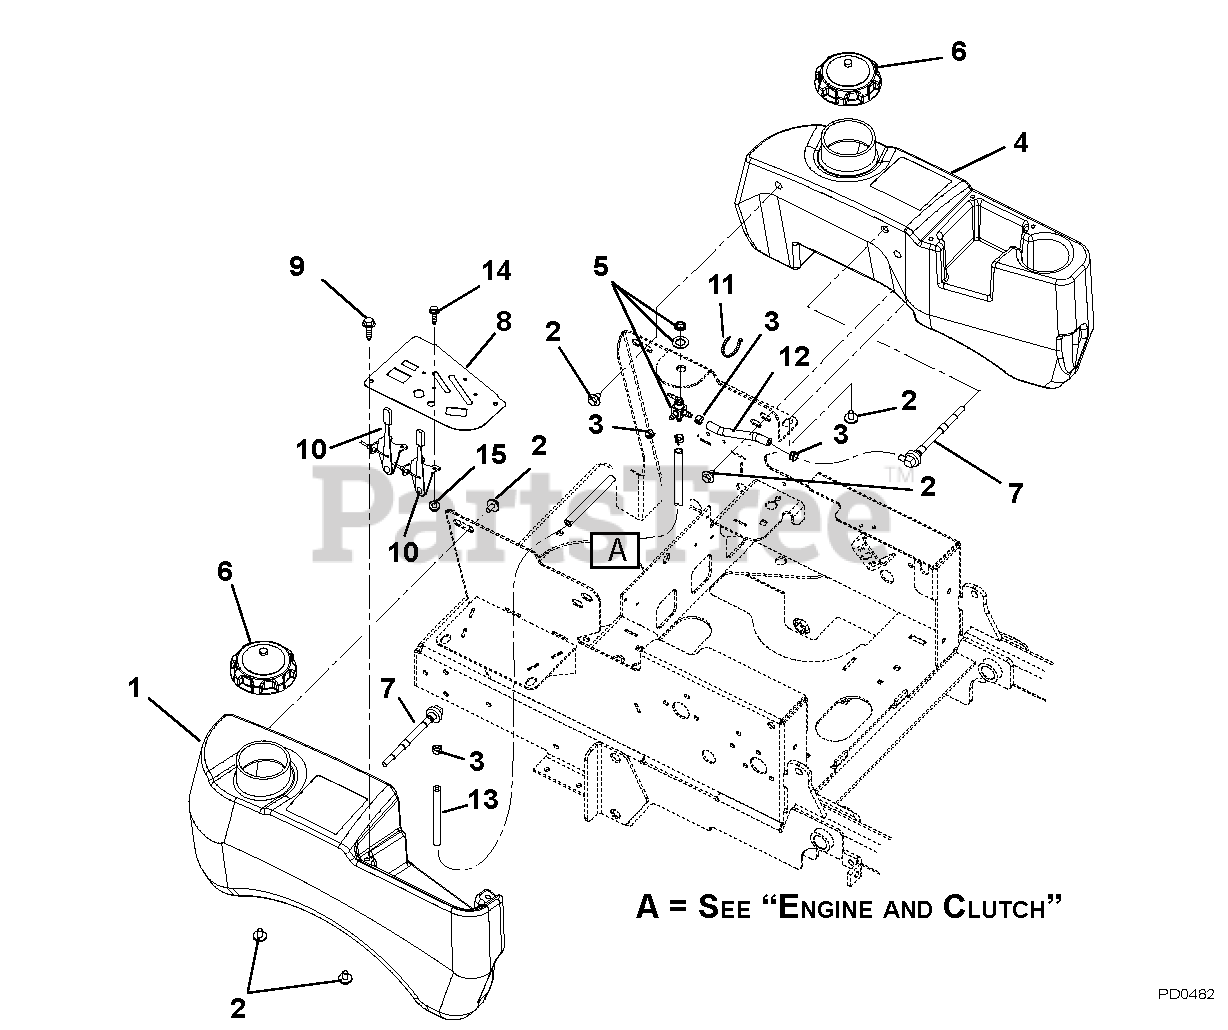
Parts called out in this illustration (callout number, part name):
1	Tank, Fuel RH (S/N 101 – 2499)
1	Tank, Fuel RH (S/N 2500 and up)
2	Bolt, SEMS .31-18 x .62
3	Clamp, Fuel Line
4	Tank, Fuel LH (S/N 101 – 2499)
4	Tank, Fuel LH (S/N 2500 and up)
5	Valve, Fuel
6	Cap, Fuel (S/N 101 – 2499)
6	Cap, Fuel Ratcheting (S/N 2500 and up)
7	Assembly, Tank Fuel Pick-up
8	Panel, Control
9	Screw, Machine 10-24 x .38 Stainless
10	Cable, Control
11	Cable Tie
12	Hose, .25 Low-PERM Bulk Gas
13	Hose, .25 Low-PERM Bulk Gas
14	Screw, Machine 10-24 x .50 Hex Washer Head
15	Nut, Locking-Nylon 10-24 with Insert
